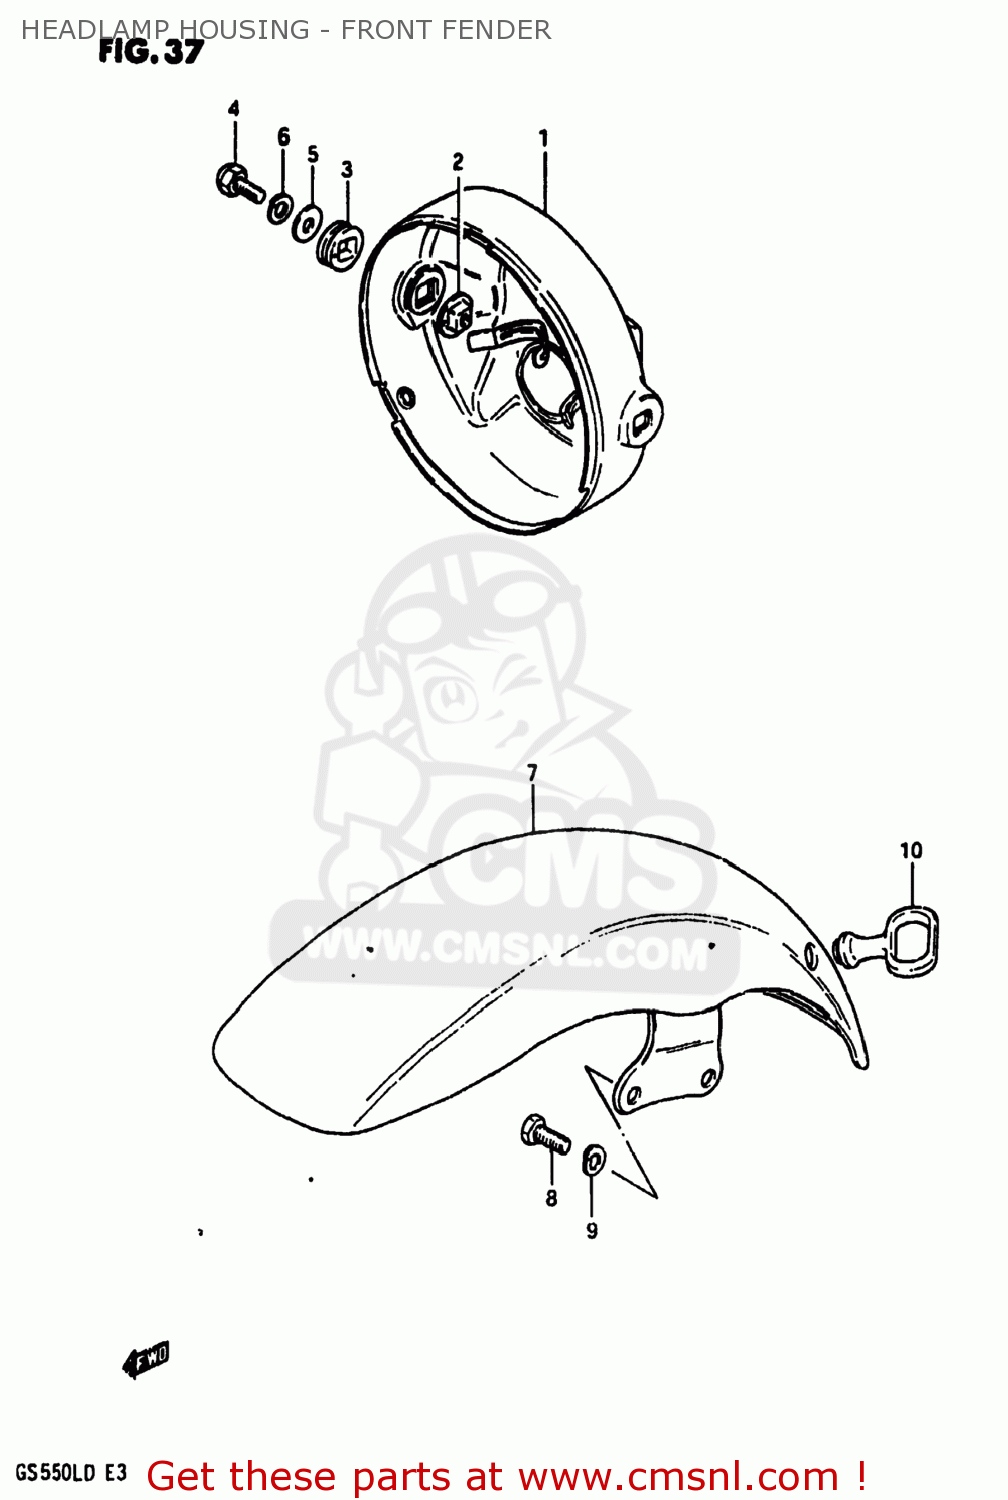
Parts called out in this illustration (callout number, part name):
1	HOUSING ASSEMBLY,HEADLAMP
2	SPACER,HEADLAMP HOUSING
3	CUSHION,HEADLAMP HOUSING
4	BOLT
5	WASHER
6	LOCK WASHER
7	FENDER,FRONT
8	BOLT
9	LOCK WASHER
10	GUIDE,CABLE
